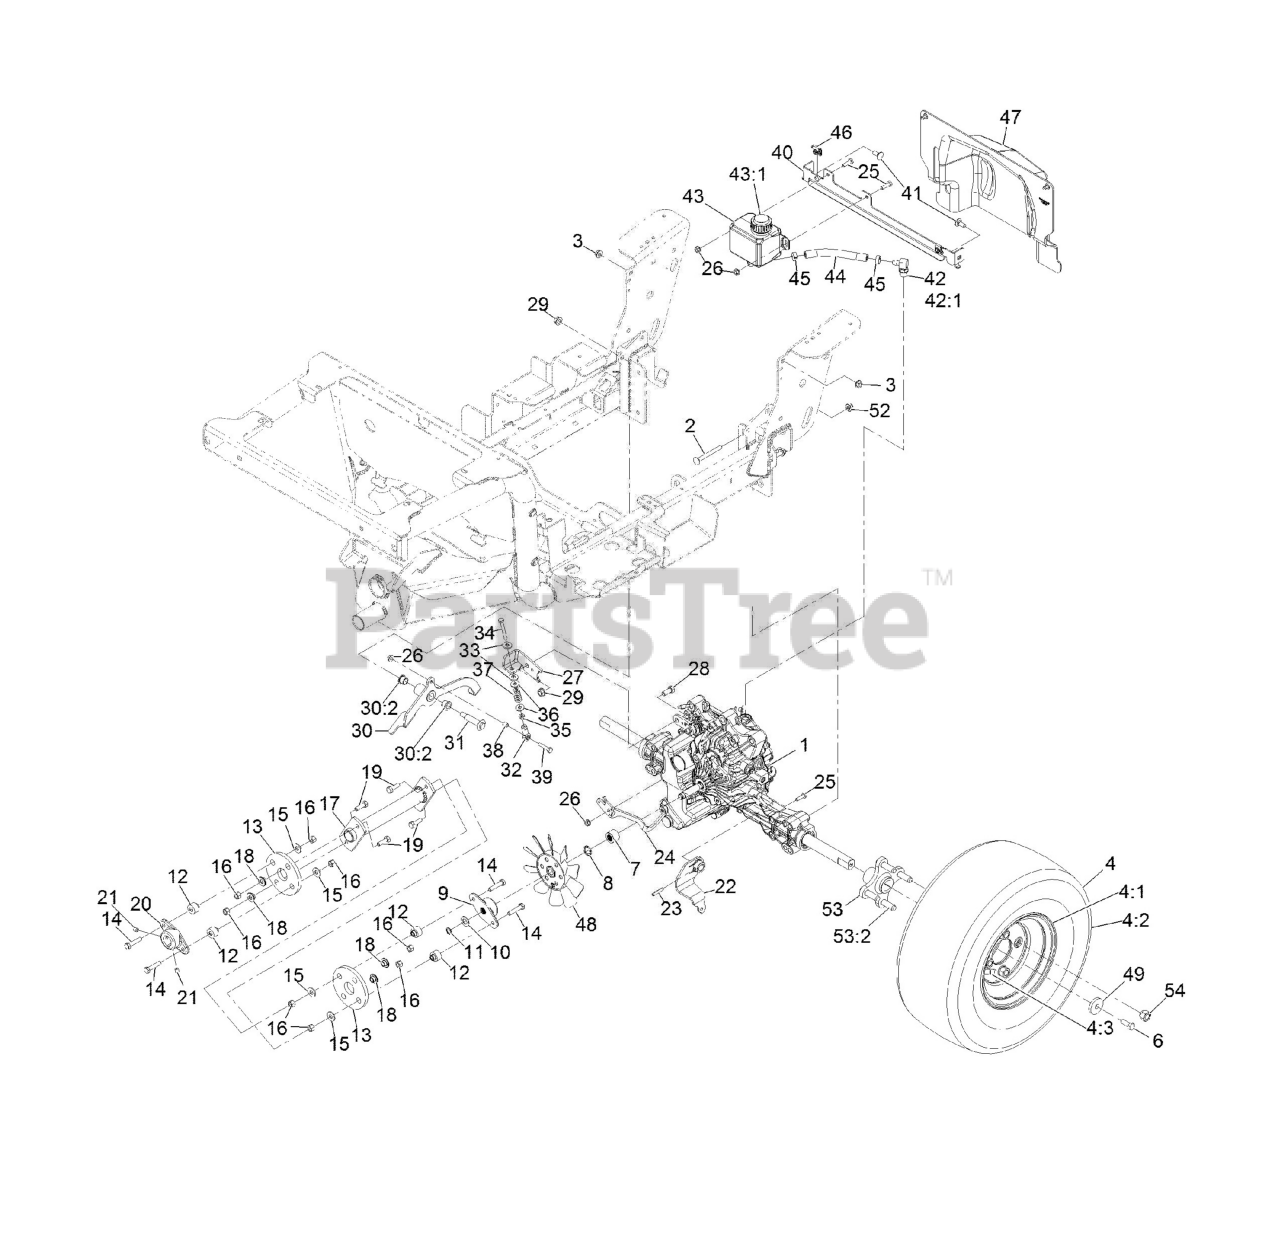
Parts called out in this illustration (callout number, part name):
1	TRANSAXLE
2	SCREW-CARR
4	Wheel And Tire ASM(18X7.5-8)
4:1	TIRE-4 PLY
4:2	Wheel, 8 X 5.375
4:3	Stem-Valve
6	SCREW-HH
7	SPACER-SHAFT, INPUT
8	WASHER-SPRING
9	HUB-SHAFT, TRANSAXLE
10	SPACER
11	RING-RETAINING
12	SPACER-COUPLING, RUBBER
13	COUPLING-RUBBER
14	SCREW-HH
15	WASHER-FLAT
16	NUT-HEX
17	Drive Shaft ASM, Welded
18	SPACER-COUPLER, RUBBER
19	SCREW-HH
20	HUB-SHAFT, ENGINE
21	SETSCREW
22	ARM-MOTION
23	PIN-SPIRAL
24	ARM-RELEASE
25	SCREW-HH
27	ARM-BRAKE
28	SCREW-HH
30	BRAKE LEVER ASM
30:2	BEARING-FLANGE
31	BOLT-SHOULDER
32	ROD END-BALL JOINT
33	WASHER-SPRING
34	SCREW-HH
35	NUT-JAM
36	WASHER-FLAT
37	SPRING-COMPRESSION
38	SPACER
39	SCREW-HH
40	BRACKET-MOUNT, TANK
41	SCREW-CARR
42	FITTING-90 DEG
42:1	O-RING
43	TANK ASM
43:1	CAP-TANK
44	HOSE-EXPANSION
46	RECEPTACLE-CLIP, MINI
47	TRANSAXLE COVER ASM
48	FAN-7 INCH
49	WASHER-CLUTCH
52	NUT-HF, NI
53	WHEEL HUB ASM
53:2	STUD-TYPE, DRIVE
54	NUT-LUG
